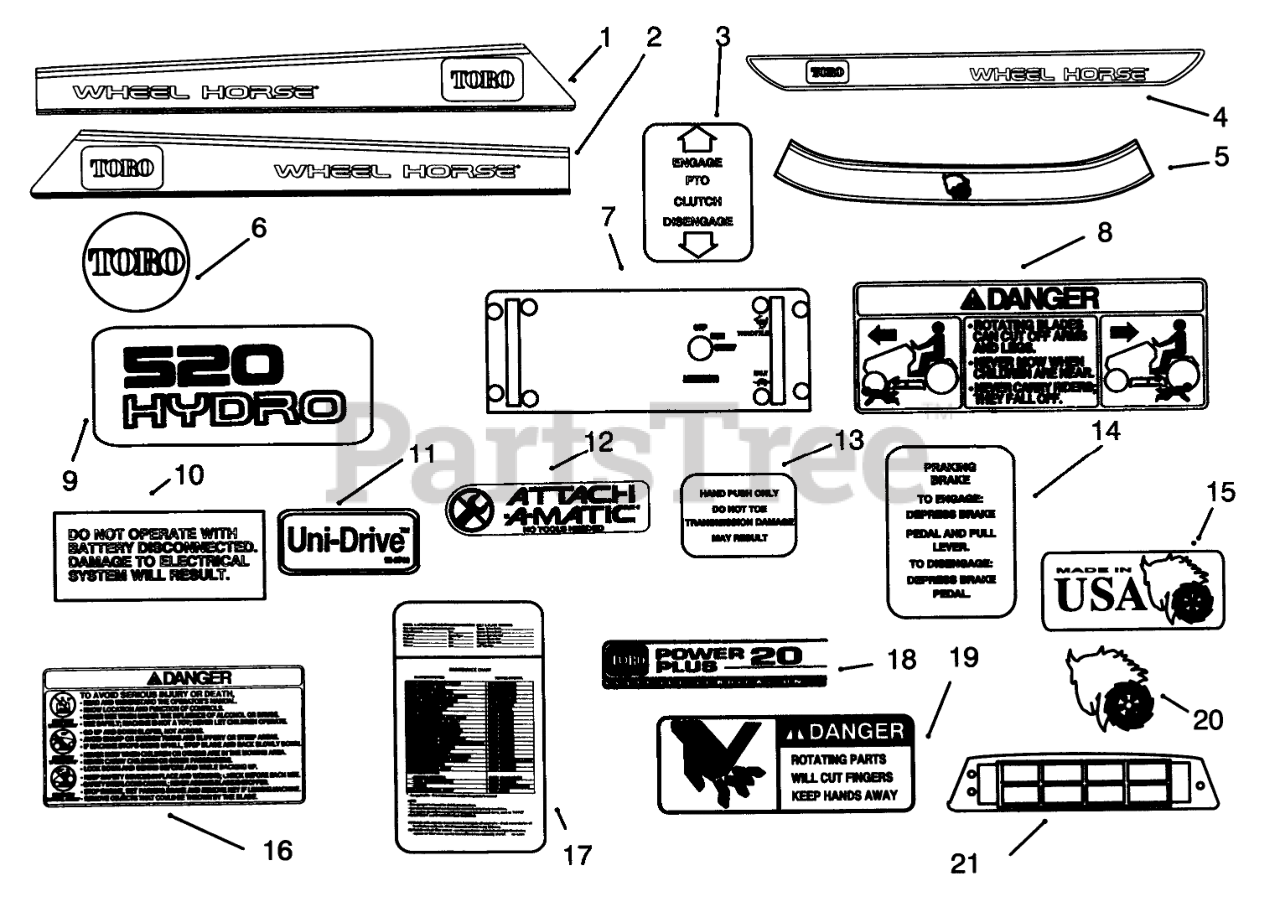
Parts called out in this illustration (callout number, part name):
1	DECAL - RH HOOD TOP
2	DECAL - LH HOOD TOP
3	DECAL PTO CLUTCH
4	DECAL - REAR FENDER
5	DECAL-FRONT HOOD, TOP
6	NAME-PLATE TORO LOGO
7	DECAL-FRONT PANEL
8	DECAL-DANGER
9	Decal-520 Hydro
10	DECAL ELECT SYSTEM
11	Decal-Unidrive
12	DECAL-ATTACH A-MATIC
13	DECAL-DO NOT TOW
14	DECAL-PARKING BRAKE
15	DECAL - USA
16	DECAL - DANGER
17	Decal-Maintenance
18	DECAL-PWR PLUS 20 PL
19	DECAL - DANGER
20	PLATE - LOGO WHL HORSE
21	DECAL-IND LIGHTS
